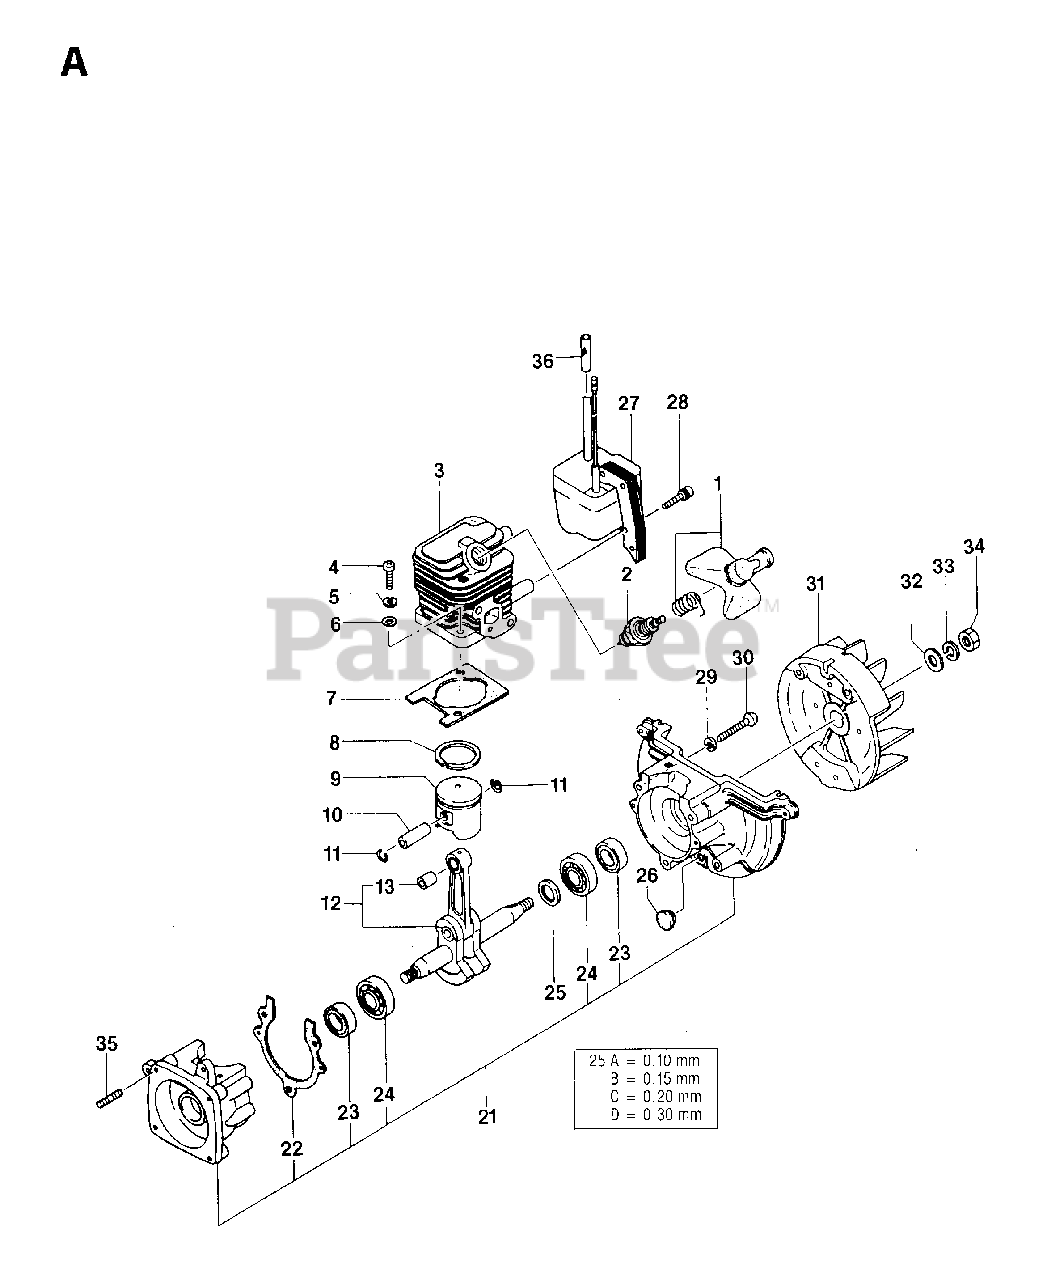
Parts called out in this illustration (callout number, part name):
2	SPARK PLUG NGK BPM7A
4	SCREW MC6S 5X20
5	SPRING WASHER
6	WASHER
29	SPRING WASHER
30	SCREW MC6S 5X30
32	WASHER BRB 8.4X17
33	SPRING WASHER
34	NUT
